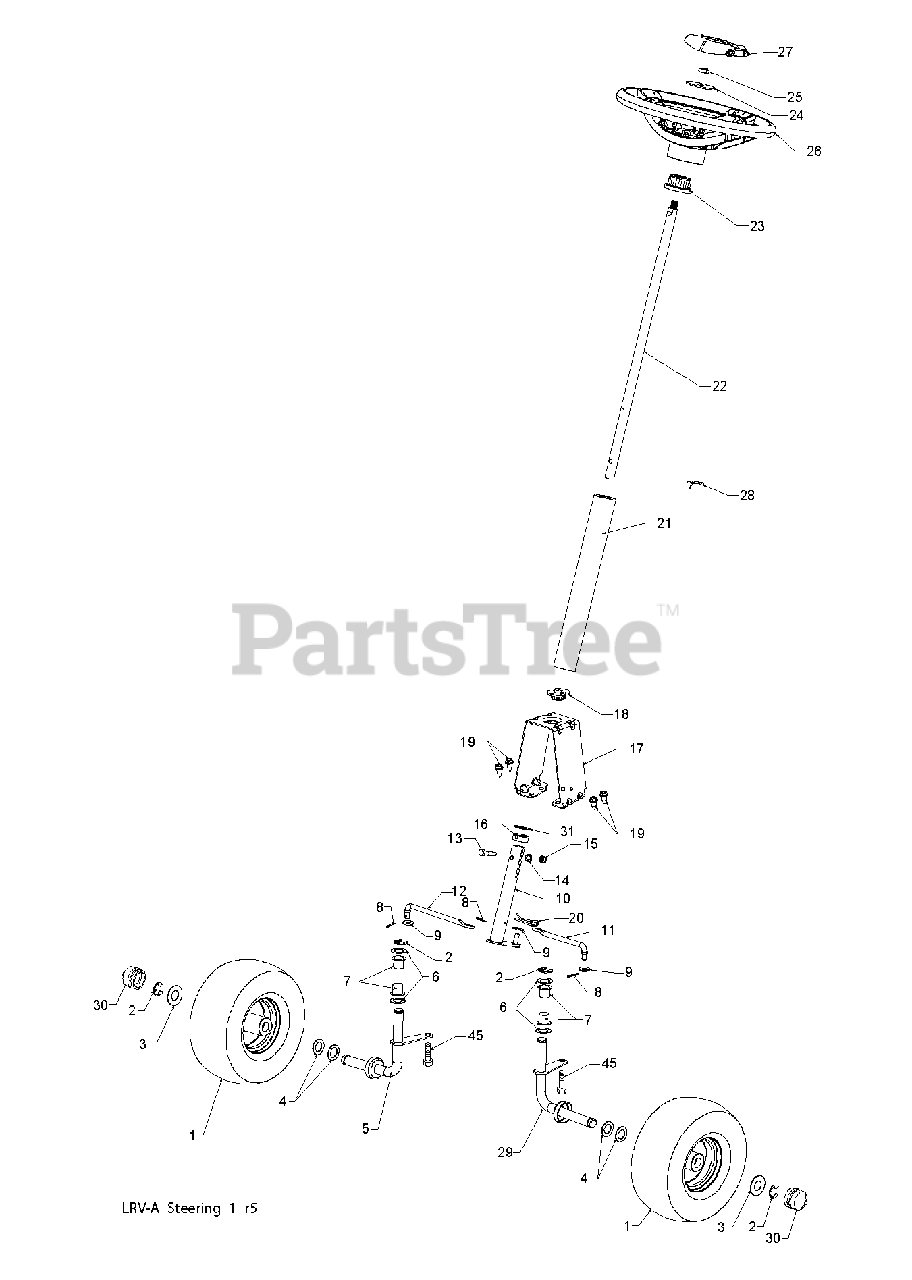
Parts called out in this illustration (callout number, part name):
1	Wheel Assembly, Front 10"
2	E-RING LT
3	WASHER.HARDENED
5	SPINDLE.STEERING.RH.LRVA
7	Steering Column Bearing
8	PIN.COTTER.5/64X3/4
10	WELDMENT, LWR STRG SHAFT
11	LINK, STRNG LH LRV
12	LINK.STEERING.RH.LRV
13	HEX BOLT
15	NUT.71038.31-18.HEX.NYLOCK
16	BUSHING, STEERING SNAP
17	SUPPORT, UPPER STEERING
18	BUSHING,STEERING
19	SCREW
20	CLIP.SPRING.STEERINGG
21	FOAM.SHAFT.STEERING
22	SHAFT, STEERING
23	STEERING.WHEEL.ADAPTER
24	WASHER 9/16"ID, 2 3/8""OD
25	NUT.HEX.1/2-20
26	WHEEL.STEER.STDR.498.OVRM.GRAY
27	CAP.WHL.STRNG.STDSRRD.SRS.GREY
28	RETAINER.CLIP.SPRING.S
29	WELDMENT.SPINDLE.LH.LR
30	CAP.HUB.AXLE.LRVA/B
45	BOLT.SHOULDER.5/16-18X
